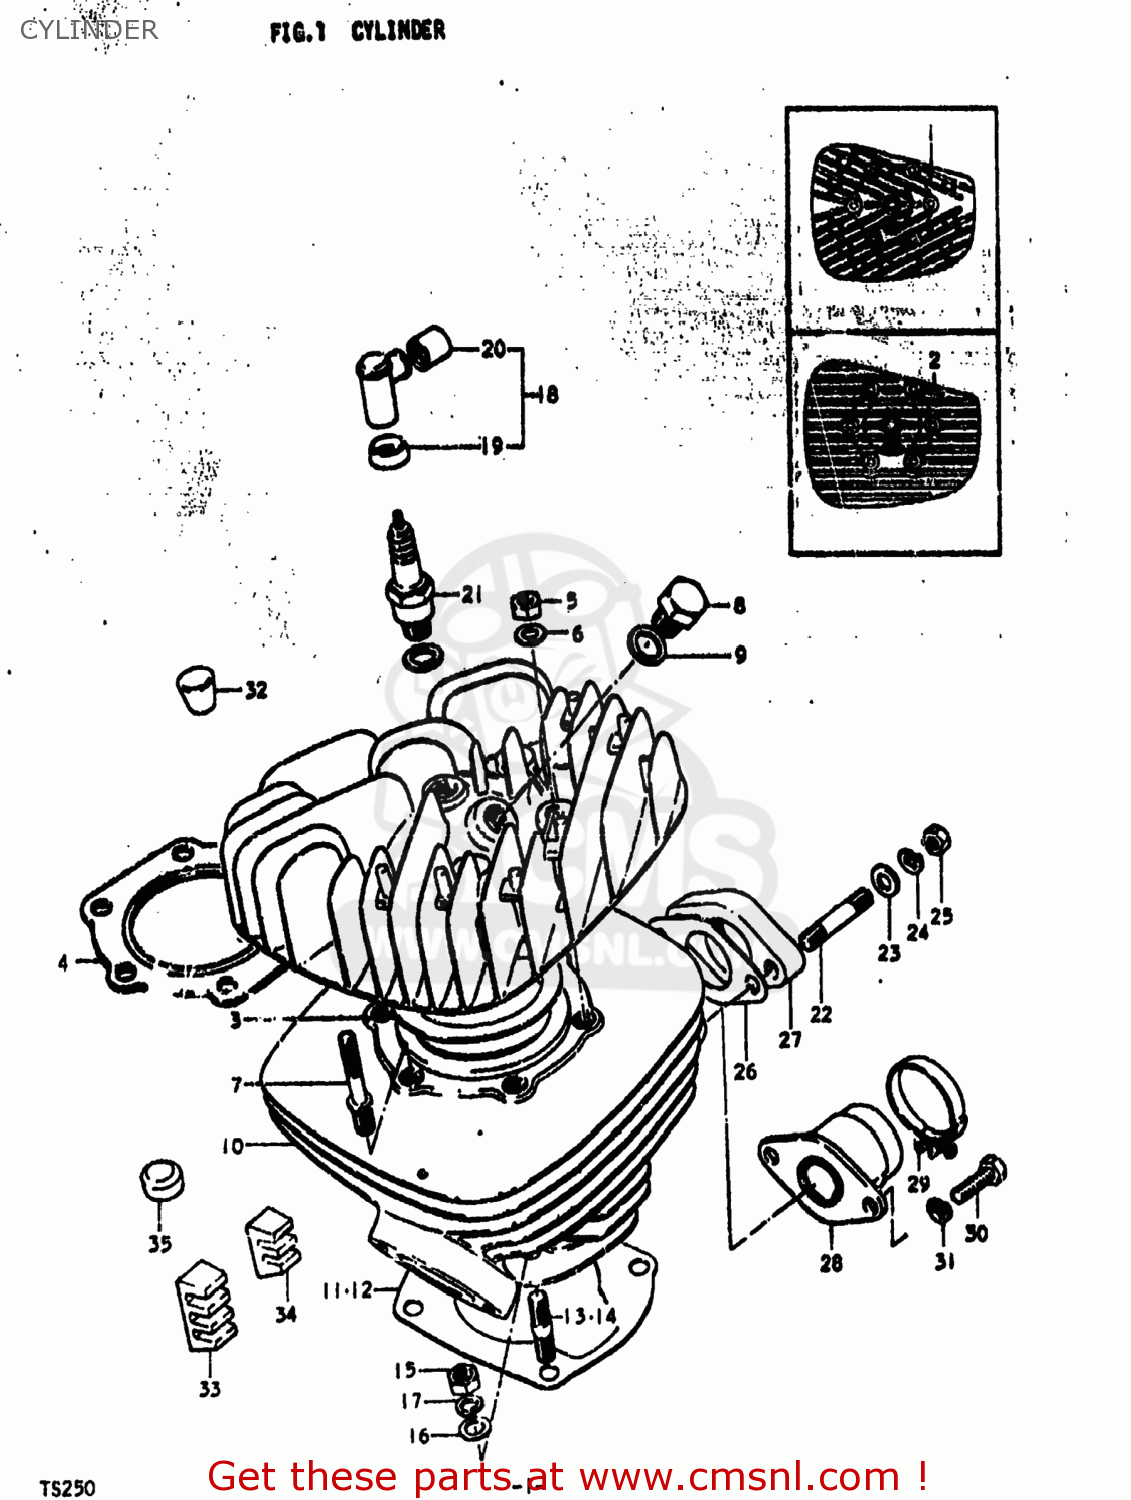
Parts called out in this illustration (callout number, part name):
1	HEAD,CYLINDER
2	HEAD,CYLINDER
3	GASKET,CYLINDER HEAD (NAS)
4	GASKET,CYLINDER HEAD (NAS)
5	NUT (8MM)
6	WASHER
7	BOLT,STUD
8	PLUG
9	GASKET(14X19.2X2) (NAS)
10	CYLINDER
11	GASKET,CYLINDER (MCA)
12	GASKET,CYLINDER (MCA)
13	STUD 10X30
14	TAPBOUT
15	NUT
16	WASHER
17	LOCK WASHER
18	CAP,SPARK PLUG
19	SEAL,SPARK PLUG
20	SEAL,SPARK PLU
21	SPARK PLUG
22	STUD BOLT
23	WASHER
24	LOCK WASHER
25	NUT
26	GASKET,CARBURETOR (NAS)
27	INSULATOR,CARBURETOR
28	PIPE,INTAKE
29	CLAMP
31	LOCK WASHER
32	PAD,CYLINDER HEAD
33	PAD,CYLINDER
34	PAD,CYLINDER
35	PAD,CYLINDER HEAD
